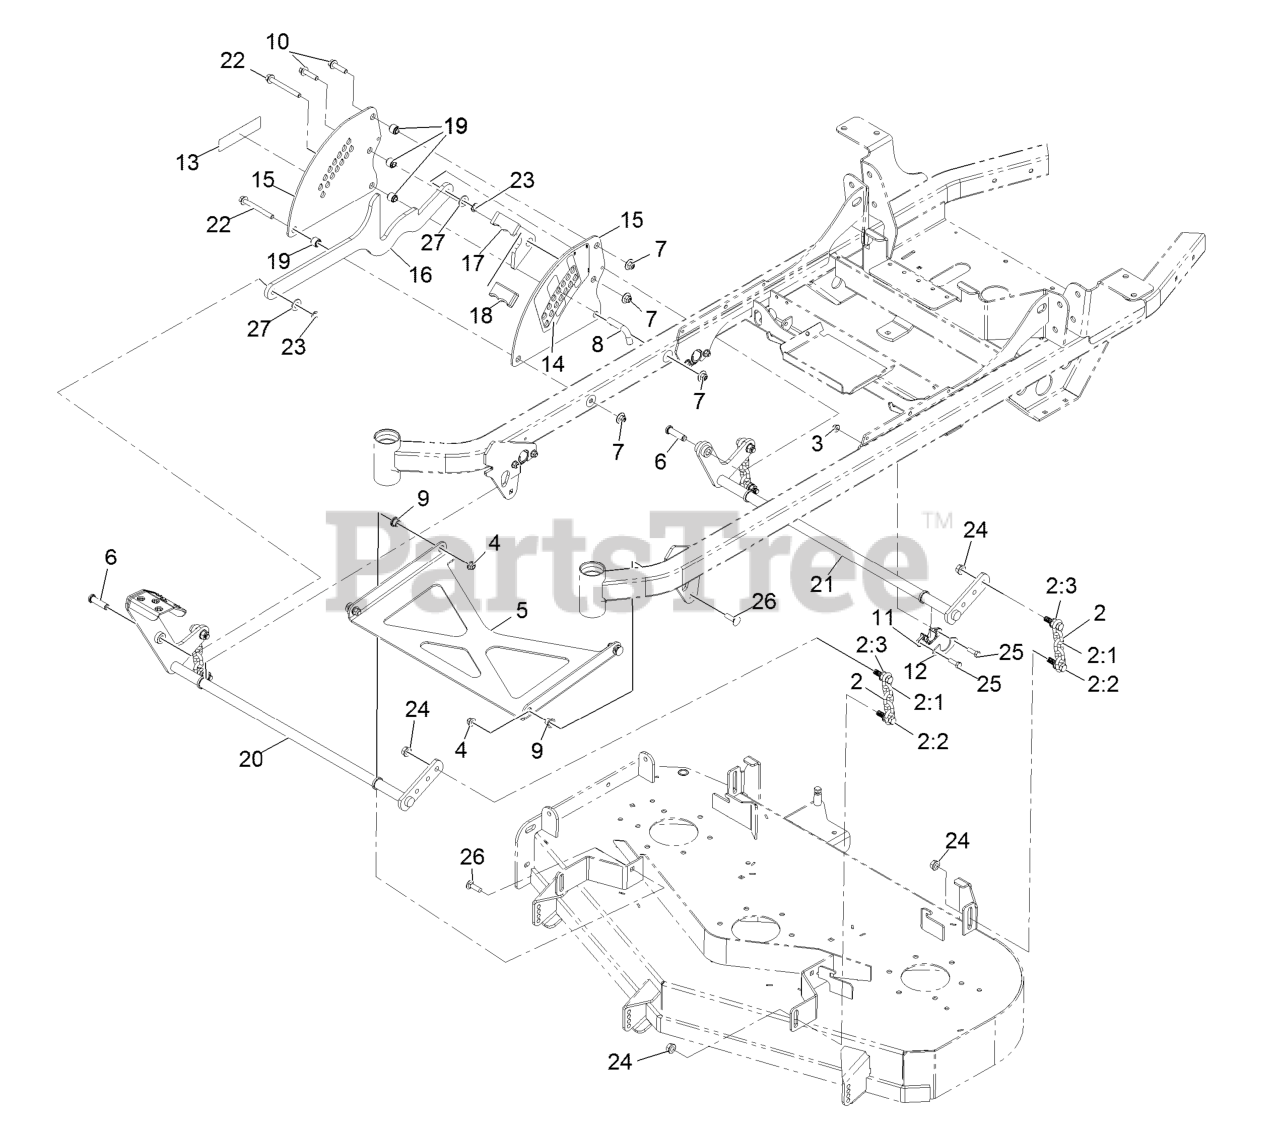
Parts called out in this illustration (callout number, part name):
2	DECK CHAIN ASM
2:1	CHAIN-LIFT, DECK
2:2	SCREW-HH
3	NUT-HF, NI
4	NUT-HF, NI
5	STRUT-DECK
6	PIN-CLEVIS
7	Nut-Nyloc 3/8-16 Flg
8	PIN-HOC
9	BUSHING-FLANGED
10	SCREW-HHF
11	BUSHING-FLANGE
12	GUSSET-LIFT, DECK
13	DECAL-S-SERIES
14	DECAL-HEIGHT OF CUT
15	PLATE,DECK LIFT
17	TRANSPORT LOCK-HOC
18	GRIP-FLAT
19	SPACER-STEP, DOUBLE
20	WLD-DECK LIFT SHAFT FRT
21	WLD-DECK LIFT SHAFT RR
22	SCREW-HHF
23	RING-RETAINING, EXTERNAL
25	SCREW-HH
26	BOLT-CARR
27	WASHER-FLAT
